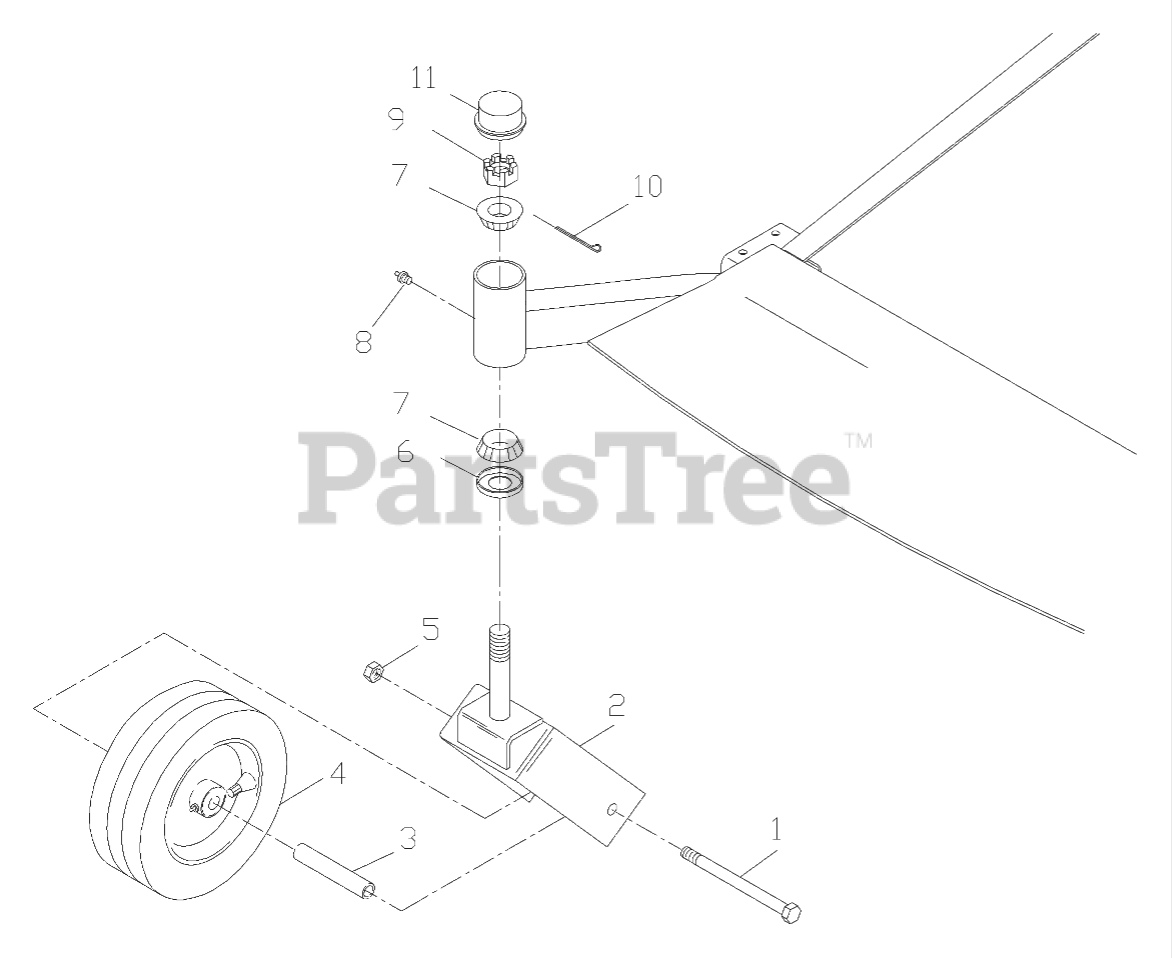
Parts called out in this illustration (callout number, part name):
1	HCS 1/2 X 7.5
2	CASTER YOKE
3	AXLE SPACER
4	TIRE
4	RIM
4	ROLLER BEARING
5	NUT 1/2 NYLOC
7	BEARING W/CUP
8	ZERK
9	NUT 1.0 CASTLE
10	COTTER PIN 1/8 X 2
11	GREASE CAP
